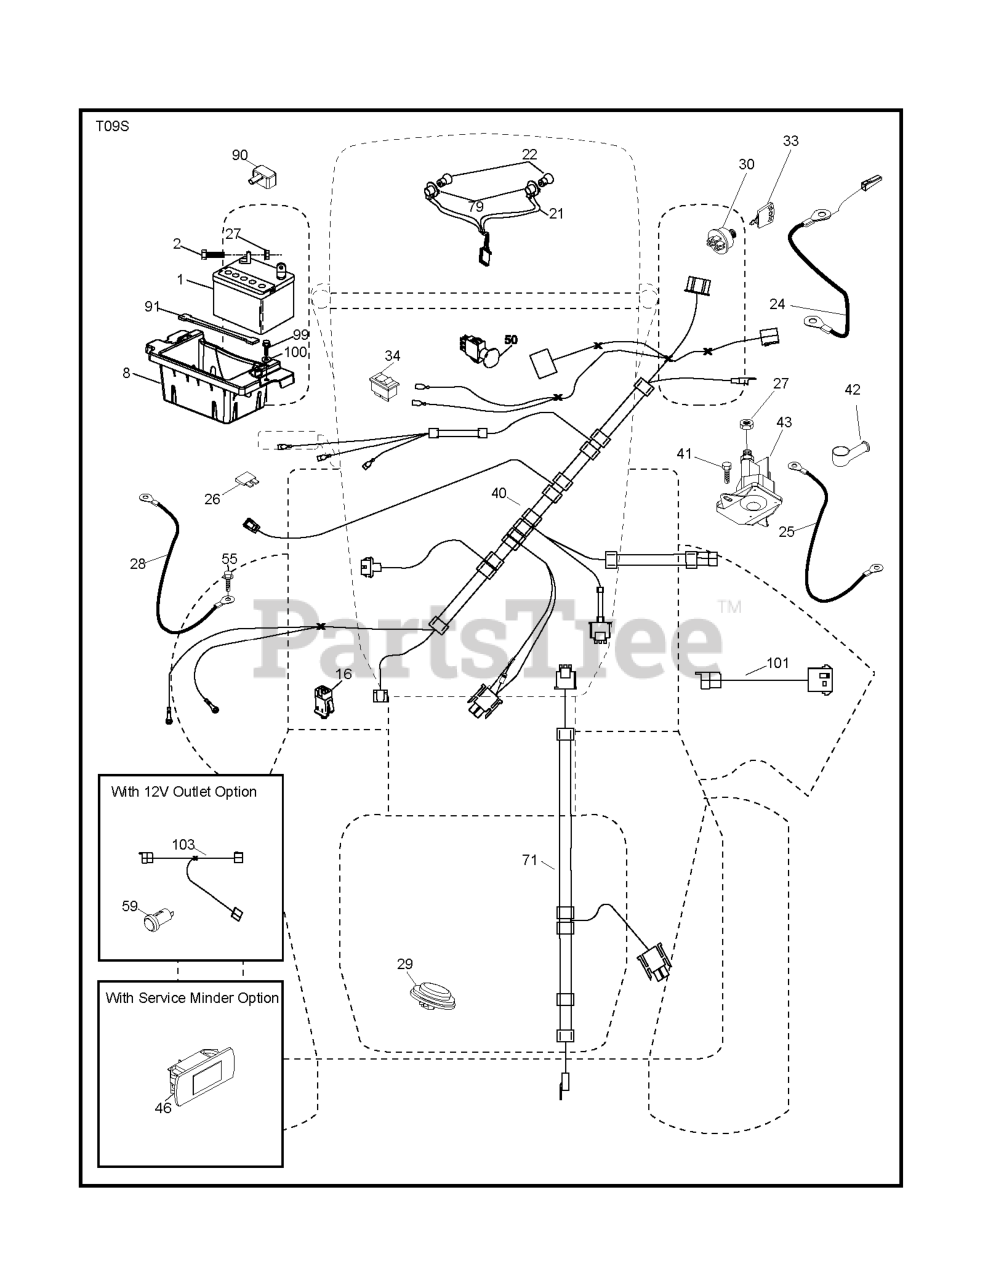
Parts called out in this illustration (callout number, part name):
1	BATTERY 12V .35 AMP
2	BOLT.HEX.1/4.X.3/4.DICHROMATE
8	BOX.BATTERY.MOUNT.FRONT.LT
16	SWITCH INTERLOOK PUSH-IN
21	HARNESS ASSY LIGHT
24	CABLE.BATT.POS.WIRE.TG.DA SOL
25	CABLE.STARTER.6G.BL/RED.17.5
26	FUSE 20AMP
27	NUT
28	CABLE GROUND 6 GA 21" 90T BLK
29	SWITCH.SEAT.DELTA.OPC.
30	SWITCH.IGN.DELTA.W.LGH.ROS
33	KEY.CHAIN.BLISTER.PACK.GEN.INT
40	HARNESS.IGN.DASH.HUQ/P
41	SCREW
42	TERMINAL COVER
43	SOLENOID.W/BRASS.PLUNGER
50	RP.PTO.SWITCH.8 TERMINAL.BLACK
55	Screw 5/16-18 x 1/2 Hex, Self Tapping 5/16-18 x 1/2
71	HARNESS-CHASSIS SUB
90	COVER.TERMINAL.BATTERY
91	STRAP.BATTERY.MOUNT.FRONT(2 2)
99	SCREW HEXWSHR 1/4-20X3/4
101	PIGTAIL.MATNLK.NEW.HAR
